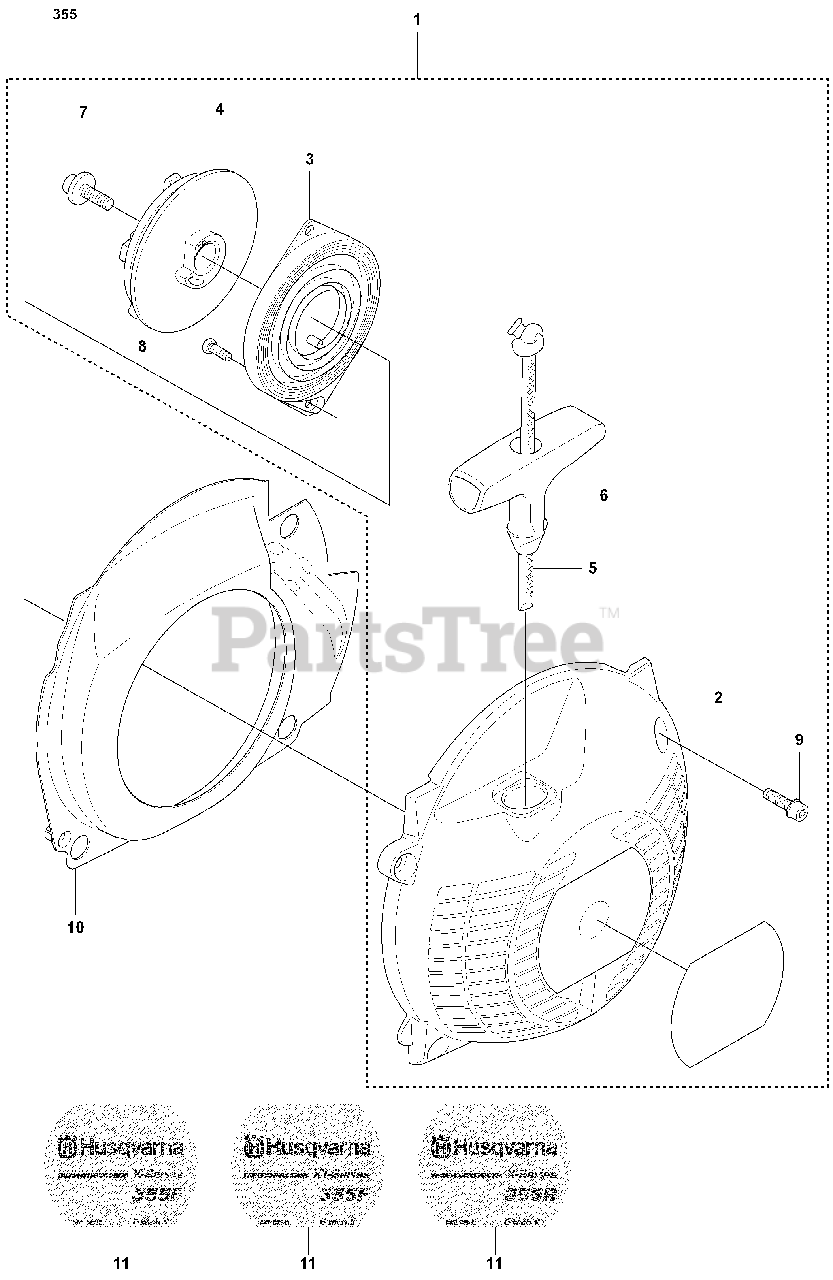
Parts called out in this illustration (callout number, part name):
2	STARTER HOUSING
3	RECOIL SPRING
4	STARTER PULLEY
5	STARTER ROPE
10	AIR CONDUCTOR
11	LABEL
